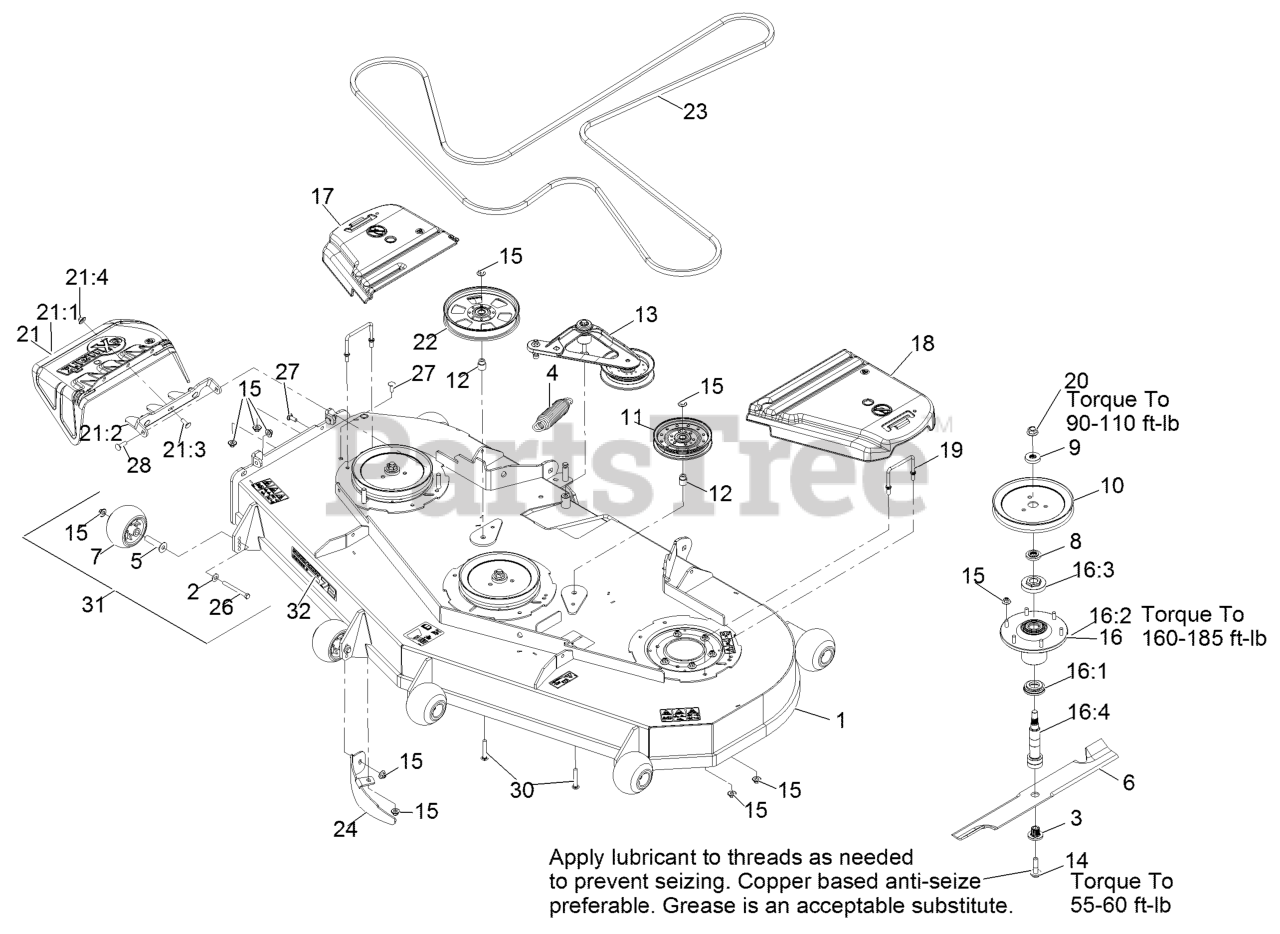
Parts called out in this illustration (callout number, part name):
1	ASM,DECK W/DECALS 724
2	WASHER-BELLEVILLE
3	BUSHING,SPLINED
4	SPRING-EXTENSION
5	AXLE, ROLLER
7	ROLLER-SCALP, ANTI
8	SPACER,SPLINED STEPPED
9	SPACER,SPLINED
10	SHEAVE,BLADE DRIVE 9.00
12	BUSHING-IDLER
13	DECK IDLER ASM
14	SCREW,SEMS 1/2-20 X 2.19
15	Nut-Nyloc 3/8-16 Flg
16	ASM,SPINDLE HOUSING
16:1	GUARD,BOTTOM
16:2	ASM,CUTTER HOUSING
16:3	NUT, SPINDLE 7/8-14
16:4	SPINDLE,DOUBLE SPLINE
17	COVER-BELT, RH
18	COVER-BELT, LH
19	WIREFORM-COVER
20	NUT-FLANGE, CENTERLOCK
21	ASM,DISCHARGE CHUTE
21:1	CHUTE,DISCHARGE
21:2	BRACKET,DISCHARGE CHUTE
21:3	SCREW-CARR
21:4	Nut-Nyloc 3/8-16 Flg
22	PULLEY-IDLER, FLAT
23	BELT-V
24	BAFFLE-DOGLEG, LZ72
26	SCREW-HH 3/8-16 X 3 3/4 GR 8
27	SCREW-CARR
28	Bolt-Carriage 3/8-16 X 1 1/4
30	SCREW-CARR
31	KIT, ANTI-SCALP ROLLER
32	DECAL, 726
